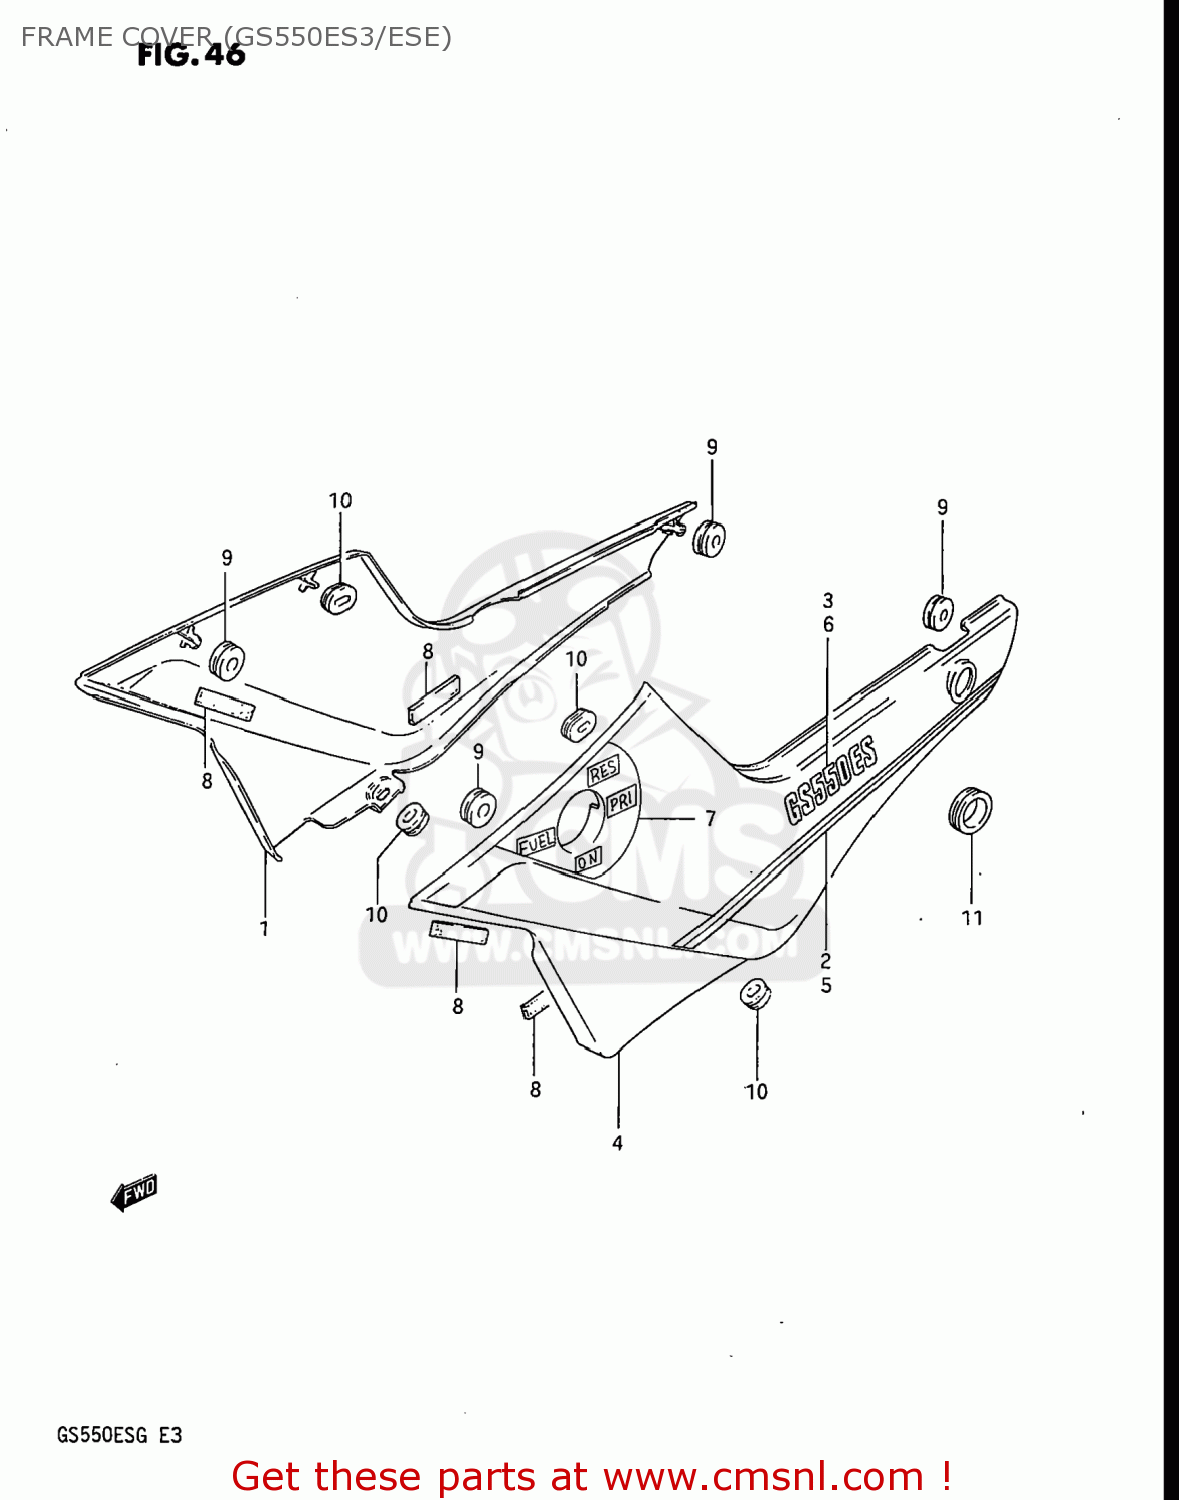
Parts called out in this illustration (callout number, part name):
1	COVER,FRAME,RIGHT
2	TAPE SET,FRAME COVER
3	EMBLEM
4	COVER,FRAME,LEFT
5	TAPE SET,FRAME COVER
6	EMBLEM
7	EMBLEM,FUEL COCK
8	RUBBER,FRAME COVER
9	CUSHION
10	CUSHION
11	GROMMET,SEAT LOCK HOLE
